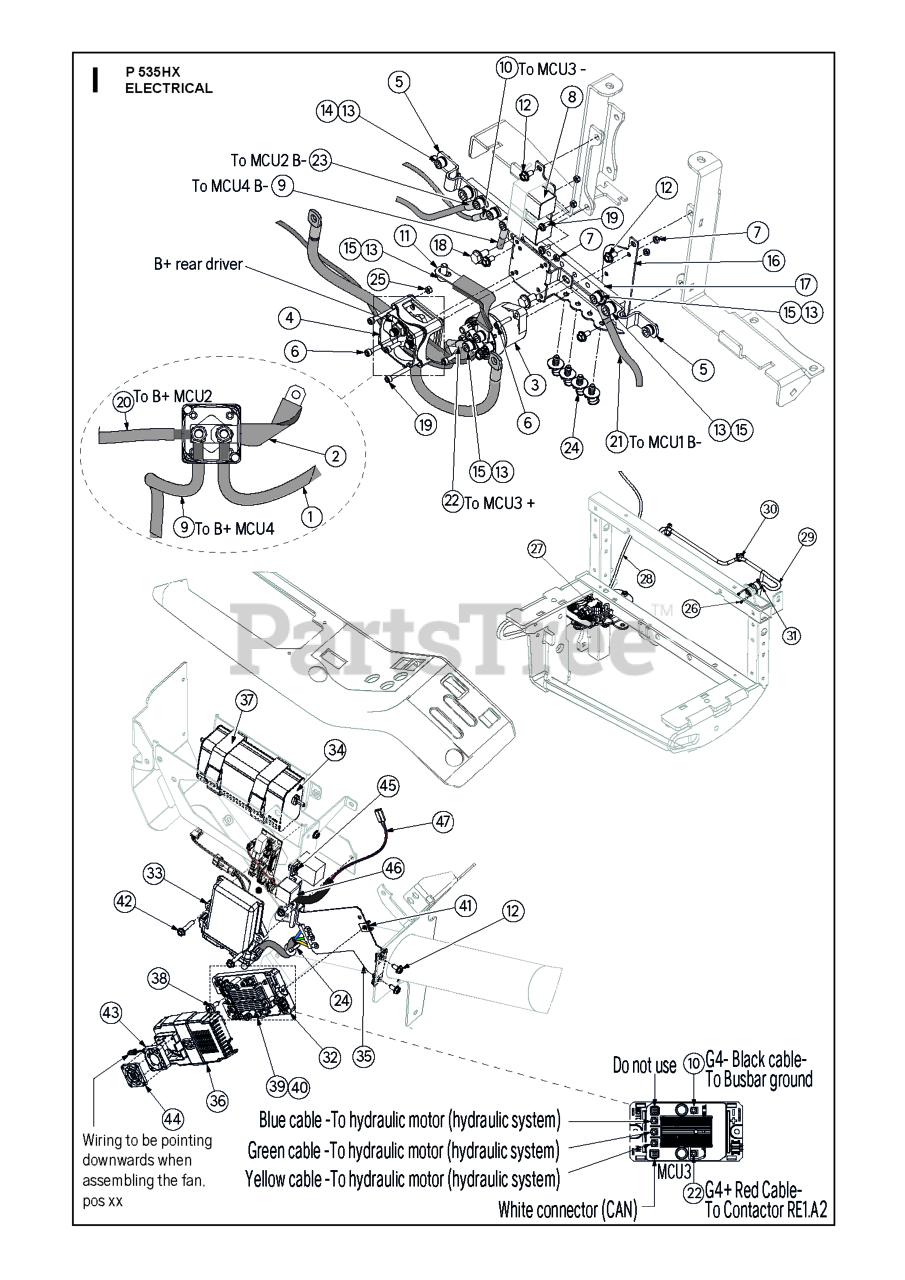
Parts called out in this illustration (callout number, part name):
7	LOCKNUT M5
12	SCREW EHHFM
31	NUT M6M M3
